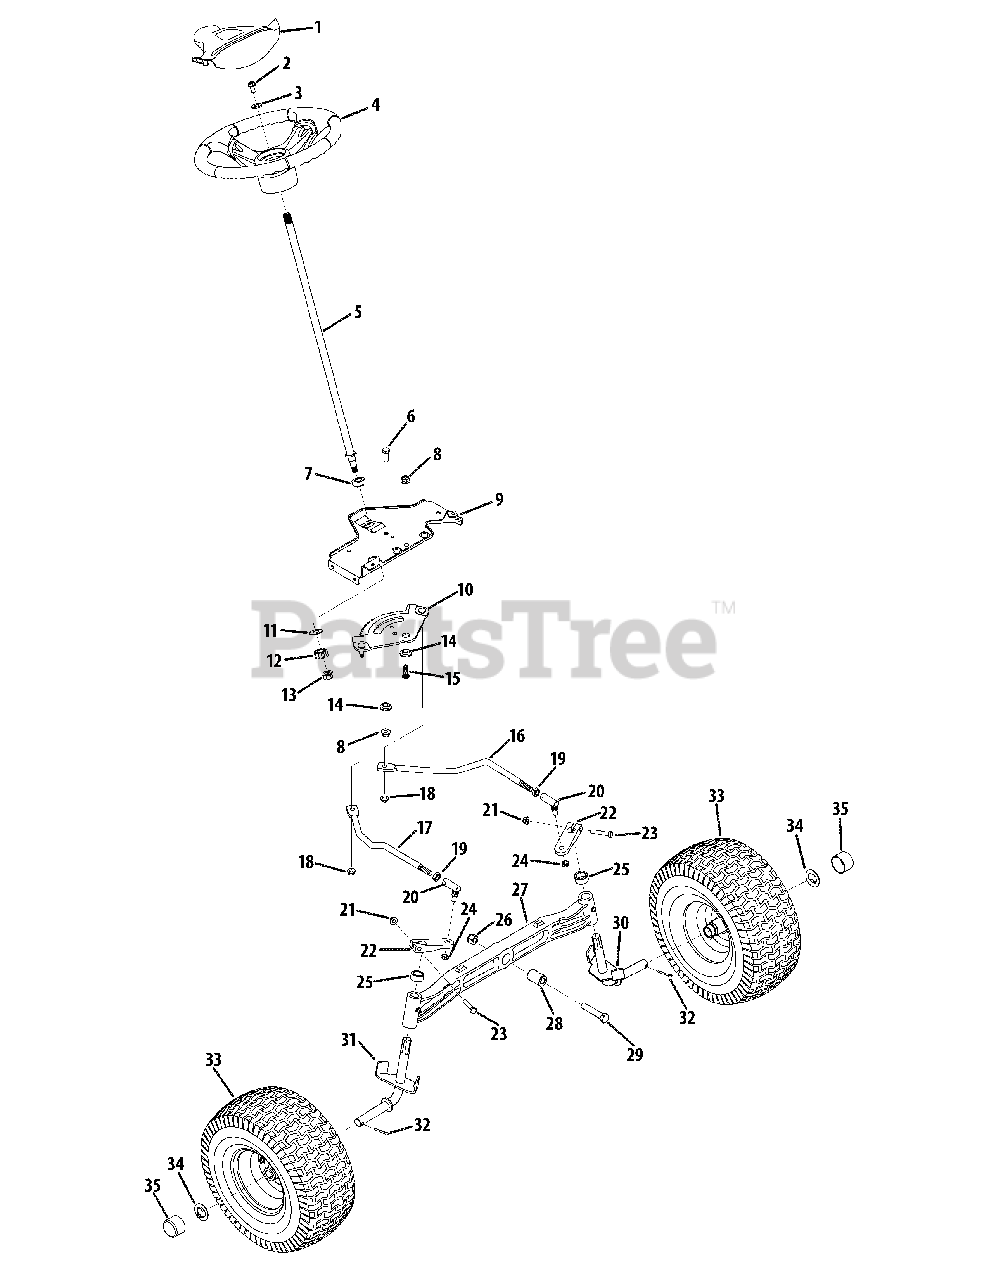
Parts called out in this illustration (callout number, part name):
1	Steering Wheel Cover
2	Hex Washer Screw, 5.16-18 x .875
2	Hex Washer Screw, 5.16-18 x .750
3	Flat Washer, .406 x .875 x .105
4	Steering Wheel
5	Steering Wheel Shaft
6	Hex Screw, 3.8-16 x 1.00
7	Hex Flange Bearing
8	Flange Lock Nut, 3.8-16
9	Steering Support Bracket
10	Steering Gear
11	Flat Washer, .51 x 1.12 x .06
12	Steering Gear
13	Flange Lock Nut, 7.16-20
14	Shoulder Spacer, .385 x 1.25 x .3025
15	Hex Screw, 3.8-16 x 1.00
16	LH Drag Link
17	RH Drag Link
18	Flange Lock Nut, 5.16-18
19	Jam Nut, 7.16-20
20	Lock Joint
21	Flange Lock Nut, 5.16-18
22	Steering Block
23	Hex Screw, 5.16-18 x 1.75
24	Hex Lock Nut, 3.8-24
25	Spacer, .71 x .125 x .56
26	Hex Lock Nut, 1.2-13
27	Axle Pivot Bar
28	Spacer, .510 x 1.00 x 1.5075
29	Hex Screw, 1.2-13 x 2.5
30	LH Axle Assembly
31	RH Axle Assembly
32	Cotter Pin, 5.32 x 1.25
33	Wheel Ass’y, Complete, 15 x 6 x 6
33	Rim Assembly
34	Flat Washer, .781 x 1.590
35	Bumper Cap
